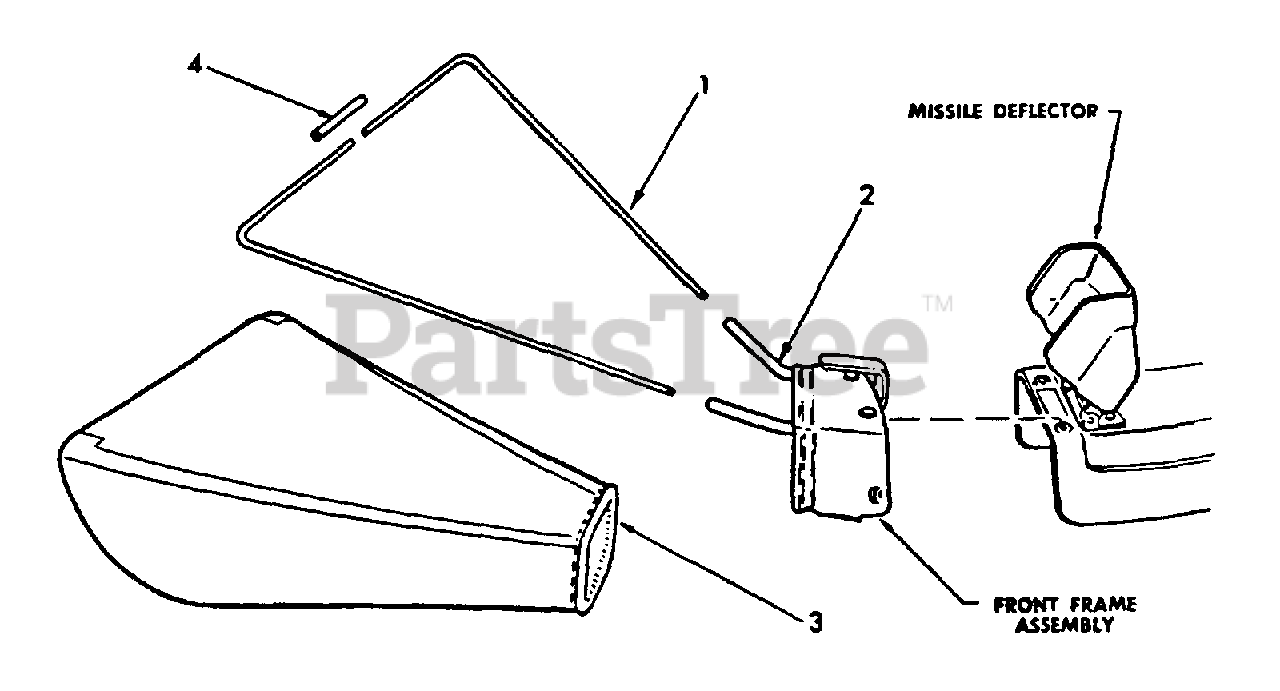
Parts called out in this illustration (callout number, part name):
1	SUPPORT, GRASS CATCHER
2	FRAME PACKAGE, GRASS CATCHER
3	BAG, GRASS CATCHER
4	TUBE, FRAME COUPLER
